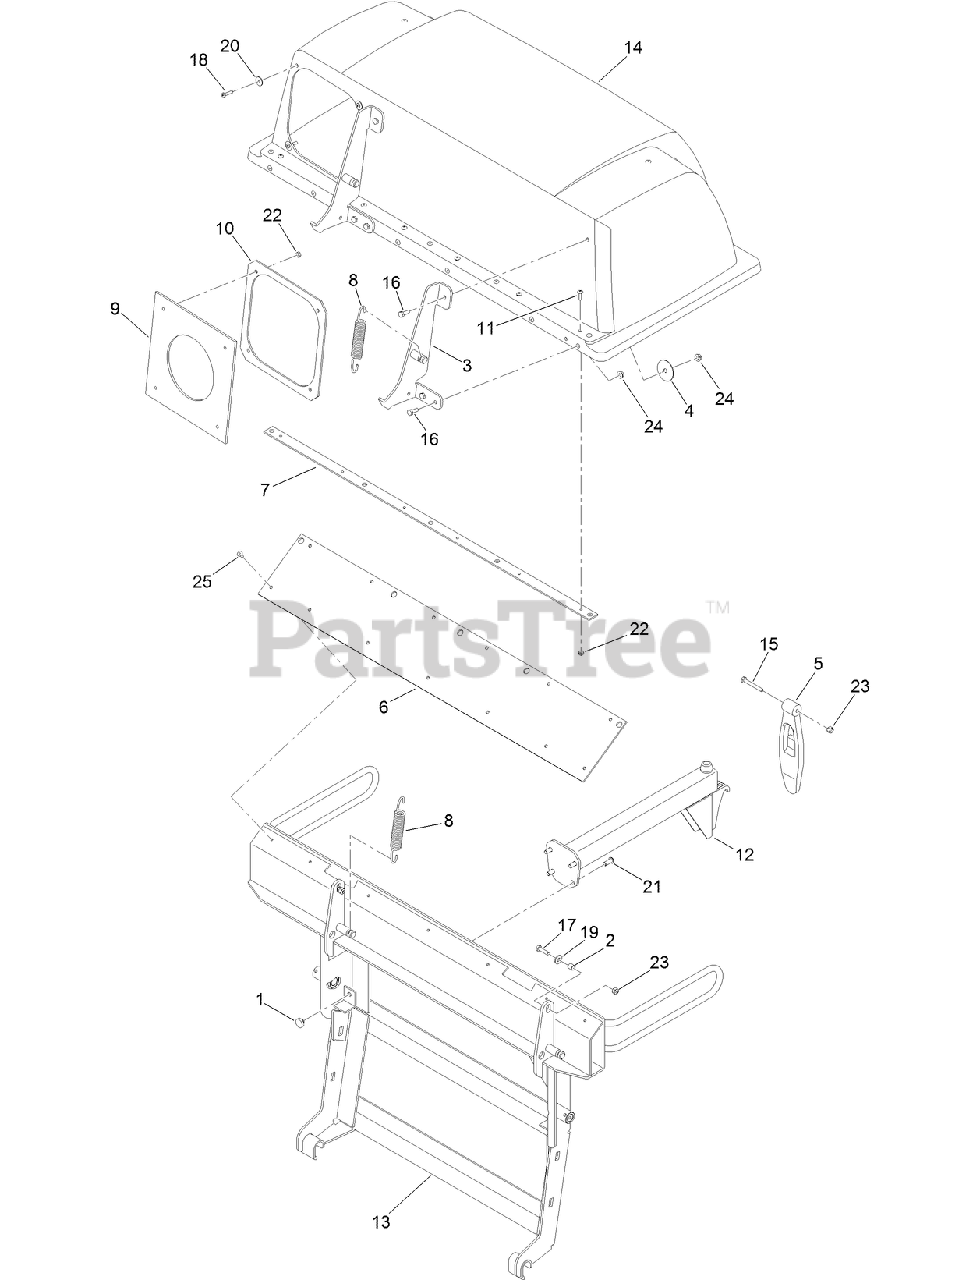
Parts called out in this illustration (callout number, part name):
1	BUMPER
2	SPACER
3	HINGE ASM
4	WASHER
7	PLATE-BACKING
8	SPRING-EXTENSION
9	SEAL-CHUTE
10	CLAMP-SEAL
11	SCREW-HEAD, TRUSS
12	BAG SUPPORT ASM
13	FRAME-BAG, TWIN
14	HOOD ASM
15	SCREW-HH
16	SCREW-HH
17	SCREW-HH
18	SCREW-PPH
19	WASHER-FLAT
20	WASHER-FLAT
21	SCREW-HSBH
22	NUT-LOCK, NI
23	NUT-LOCK, NI
24	NUT-HF
25	RIVET-BLIND
